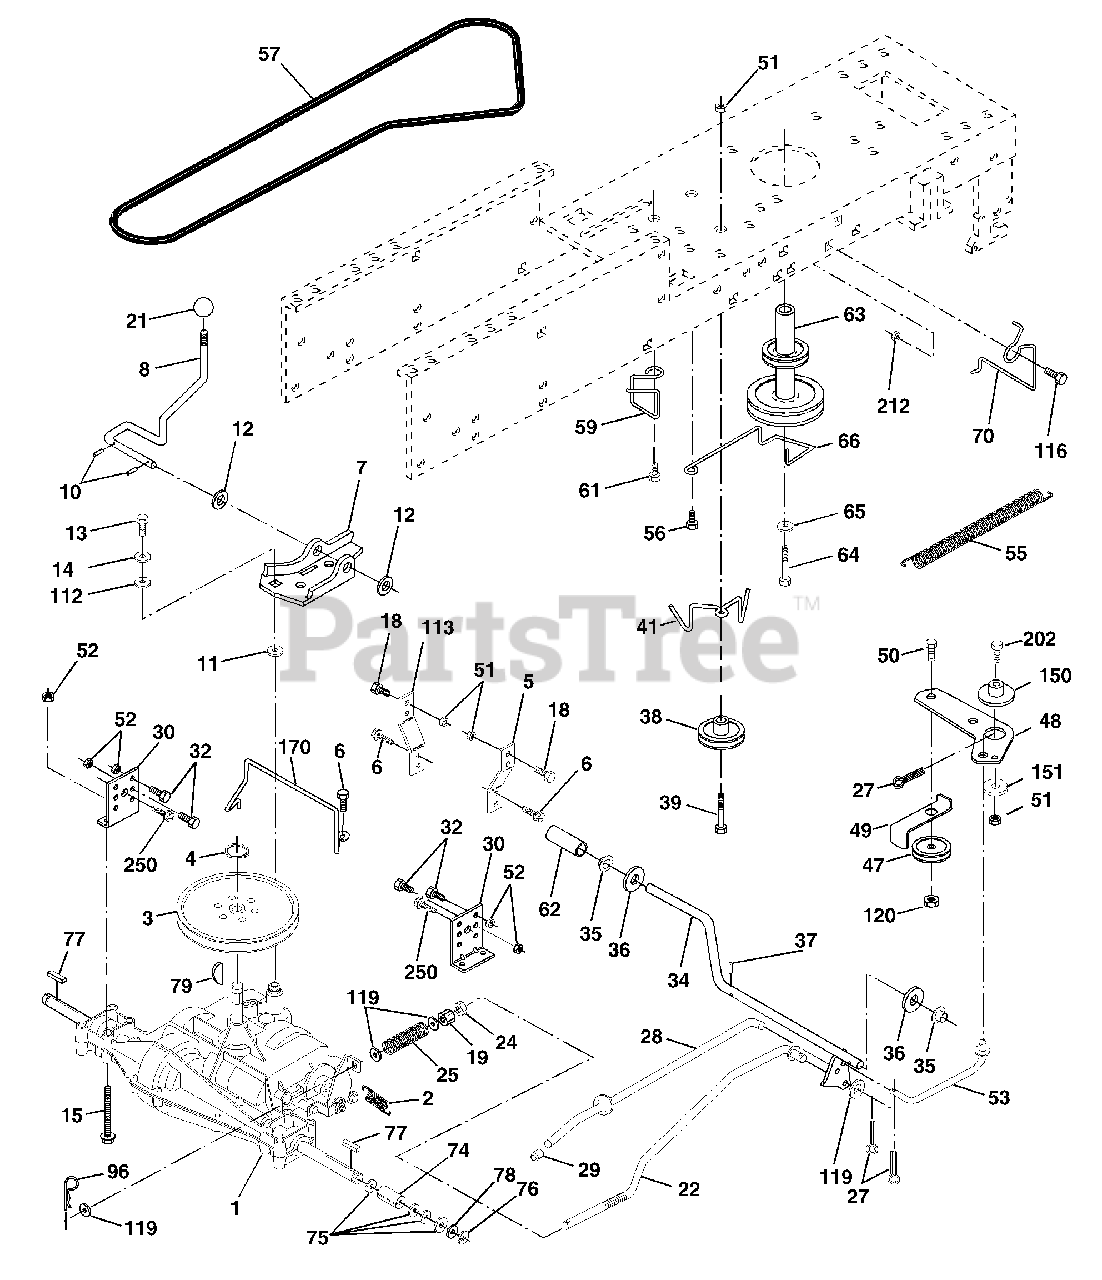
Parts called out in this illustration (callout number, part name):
2	Spring Return Brake T/a Zinc
3	Pulley Transaxle 18/20" tires
4	Ring Retainer # 5100-62
5	Strap Torque 30 Degrees
6	Screw 5/16-18 x 3/4
7	Bracket Saddle Shift T/a
8	Rod Shf Sdl LY/YT Str Blk
10	Pin Cotter 1/8 x 1 Cad
11	Washer Plate 388 Sq Hole
12	Washer 15/32 x 3/4 x 16ga
13	Bolt 1/4-28unf Gr8 W/Patch
14	Washer Lock Hvy Helical 1/4
15	Bolt Hex Flghd 5/16-18 x Gr. 5
18	Bolt Fin Hex 3/8-16 UNC x 1 Gr. 5
19	Nut Lock Hex W/Ins. 3/8-16 Unc
21	Knob Rd 1/2-13 Plstc Thds
22	Rod Brake Blk Zinc 26 840
24	Nut Hex Jam 3/8-16 Unc
25	Spring Rod Brake 2 00 Zinc
27	Pin Cotter 1/8 x 3/4 Cad
28	Rod Brake Parking Lt/Yt
29	Cap Brake Parking
30	Bracket Mtg Transaxle
32	Bolt Hex Hd 5/16-18unc x 3/4
34	Shaft Asm Pedal Foot Nibbed
35	Bearing Nylon Blk 629 Id
36	Washer 21/32 x 1 x 16 Ga
37	Pin Roll 3/16 x 1"
38	Pulley Composite Flat
39	Bolt Fin Hex 3/8-16 UNC x 3 Gr. 5
41	Keeper Belt Idler
47	Pulley Idler V Groove Plastic
48	Bellcrank Asm. Clutch
49	Retainer Belt Style Spring
50	Bolt Hex Hd 3/8-16unc x1-1/2
51	Nut Crownlock 3/8-16 UNC
52	Nut Crown Lock 5/16-18
53	Link Clutch 7 66
55	Spring Return Clutch 6 75
56	Screw 3/8-16 x 1-1/4
57	V-Belt Gd Drive 9530
59	Keeper Belt Centerspan
61	Screw 3/8-16 x .875
62	Cover Pedal Blk Round
63	Pulley Eng Cl Cable
64	Bolt Hex 7/16-20 x 4 Gr 5
65	Washer Lock Hlcl Spr 7/16
66	Keeper Belt Engine FP
70	Guide Belt Mower Drive RH
74	Spacer Axle
75	Washer 25/32 x 1-1/4 x 16 Ga
76	E-ring #5133-75
77	Key Square 2 0 x 1845/ 1865
78	Washer 25/32 x 1-5/8 x 16 Ga
79	Key Woodruff #9 3/16 x 3/4
96	Retainer Spring 1
112	Washer 9/32 x 3/4 x 10 Ga
113	Strap Torque LH LT
116	Bolt 3/8-16 x 1
119	Washer 13/32 x 5/8 x 16 Ga
120	Nut Lock Flg 3/8-16
150	Spacer Retainer
151	Washer 13/32 x 2 x 10 Ga.
170	Keeper Belt Transaxle Gear
202	Bolt Carr. Sh 3/8-16 x 1-3/4 Gr. 5
212	Nut Hex Flange Lock
250	Screw 3/8-16 x 3/4
